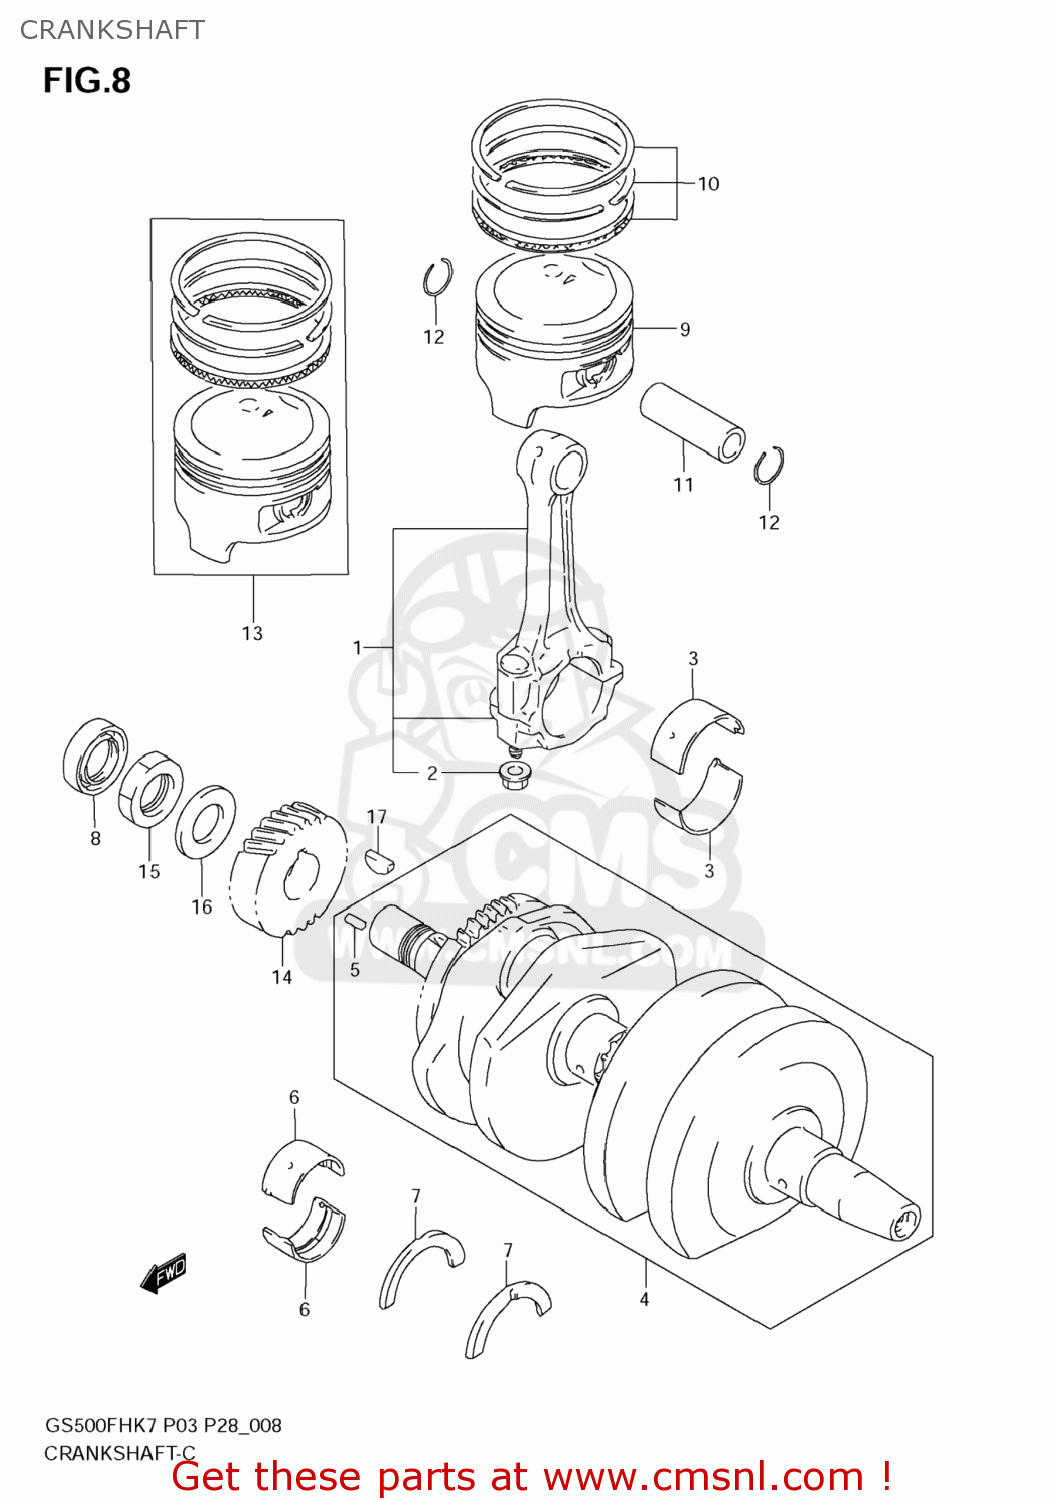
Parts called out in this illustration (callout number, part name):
1	CONNECTING ROD ASSY
2	NUT
3	BEARING,CRANK PIN
4	CRANKSHAFT
5	PIN
6	BEARING,CRANKSHAFT(GREEN)
7	BEARING,CRANK THRUST
8	SEAL,OIL(22X40X8)
9	PISTON (74.00MM)
10	RING SET,PISTON
11	PIN,PISTON (18MM)
12	CIRCLIP
13	PISTON SET(OS:0.5)
14	GEAR,PRIMARY DRIVE NO.28
15	NUT
16	WASHER
17	KEY
